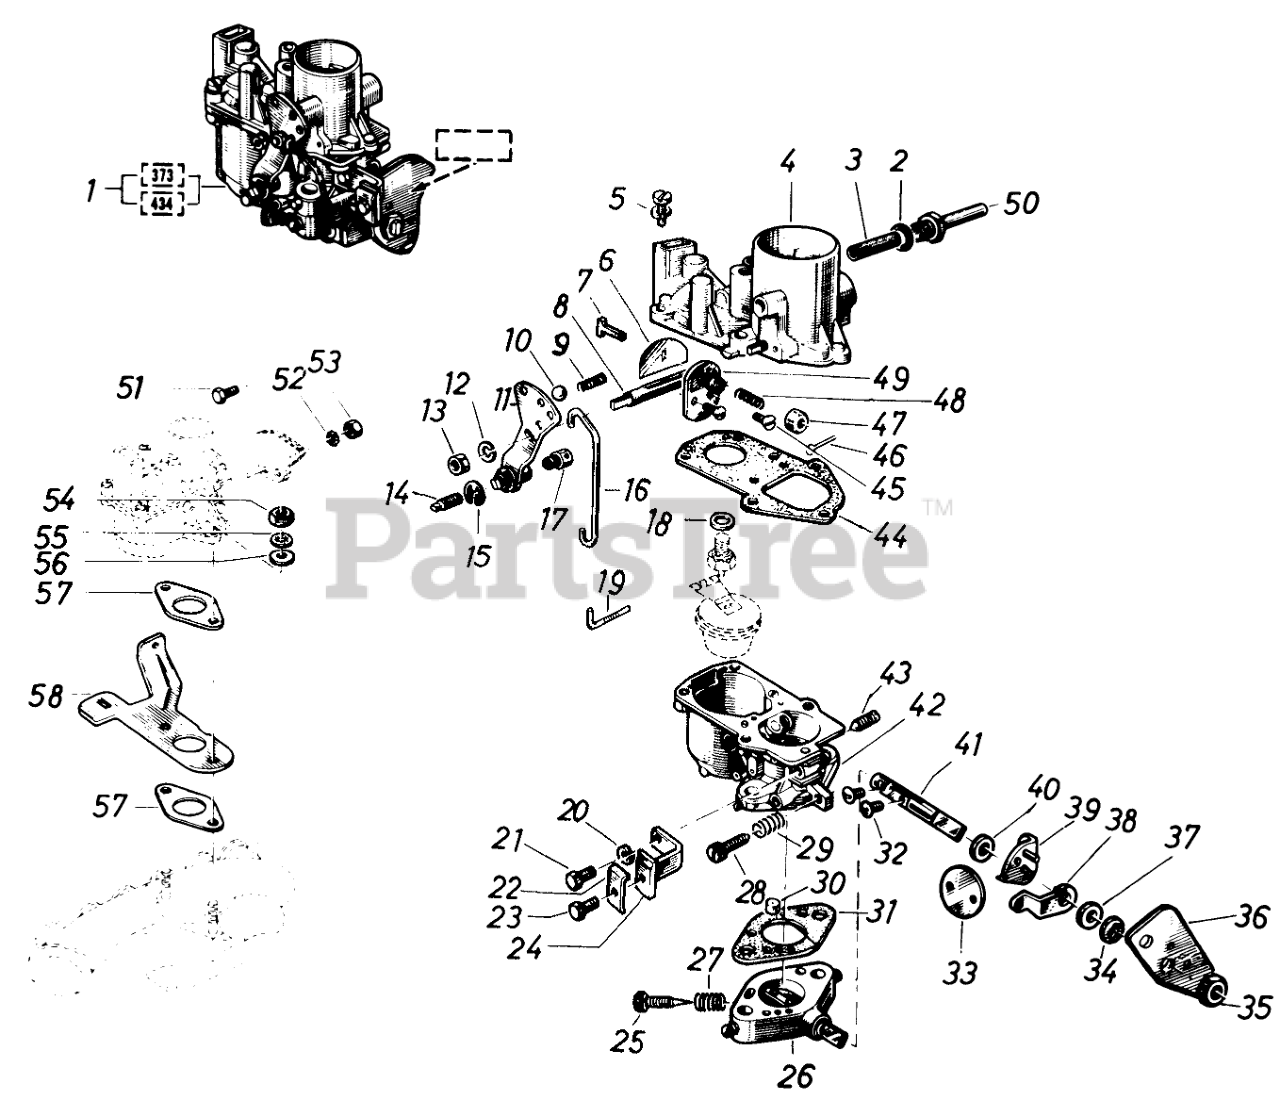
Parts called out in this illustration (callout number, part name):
1	Carburetor "Solex" Assy
2	Gasket
3	Filter
4	Carburetor Housing Upper Part
5	Screw with Lock Washer
6	Choke Flap Valve
7	Choke Valve Guide Pin
8	Choke Shaft
9	Spring
11	Lever
12	Lock Washer
15	Lock Washer
17	Screw
18	Gasket
19	Float Pin
20	Lock Washer
21	Screw
22	Clamp
23	Screw
24	Bracket
25	Adjusting Screw
26	HSG W/ THROTTLE VALV
27	Spring
28	Adjusting Screw
29	Spring
31	Gasket
32	Screw
33	Throttle Valve
34	Washer
36	Carburetor Lever
38	Lever
39	Stop Lever
40	Gasket Ring
41	Throttle Shaft
42	Float Case
43	Jet Screw
44	Gasket
45	Screw
48	Spring
49	Choke Valve
50	Gas Line Fitting
51	Screw
52	Washer
55	Washer
56	Washer
57	Gasket
58	Bracket
